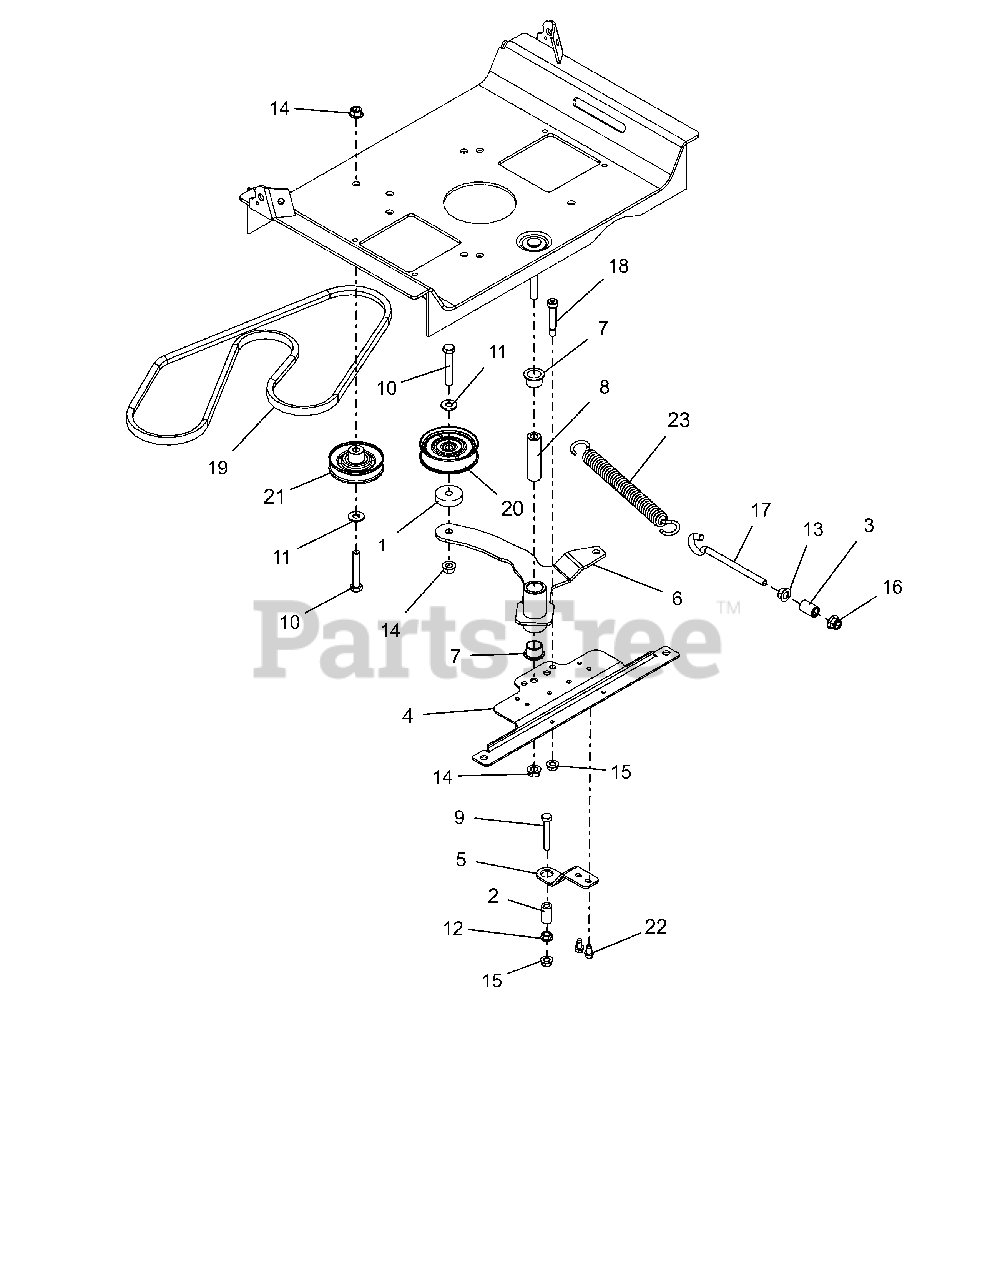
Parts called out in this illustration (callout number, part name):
1	SPACER, .39 X 1.50 X .380
2	SPACER, RUBBER 5/16 IDX1.0 LG
3	SPACER, .375X.625X.970 (PM)
4	BRKT, DRIVE IDLER MOUNTING
5	BRKT, CLUTCH STOP (XL)
6	WLDMT,GRD DRIVE IDLER ARM-LGR
7	BSHG-FLG 0.75X0.875X.625X1.125
8	BUSHING, SLEEVE .38X.750X2.78
9	@BLT-HEX .31-18X2.00 GR5 YWZC
10	@BLT-HEX .38-16X2.25 GR5 YWZC
11	@WSHR-FL-STL.38X.875X.083 YWZC
12	@NUT-SPNLK-FLG .312-18 YWZC
13	@NUT-SPNLK-FLG .375-16 YWZC
14	@NUT-LK-TOP-FLG .38-16 YWZC
15	@NUT-LK-TOP-FLG .31-18 YWZC
16	@NUT-LK-NYL-FLG .38-16 YWZC
17	BOLT,.38-16 X 4.25-.62 DIA EYE
18	BLT-SHLDR .38X1.5X.31-18 SLT Y
19	V-BELT, A-RAW EDGE
20	IDLER, FLAT - 3.05" X .75"
21	IDLER, V-3.000 OD
22	SCR-TAP .25-20X.50 HWH TR YWZ
23	SPRING, EXTENSION
